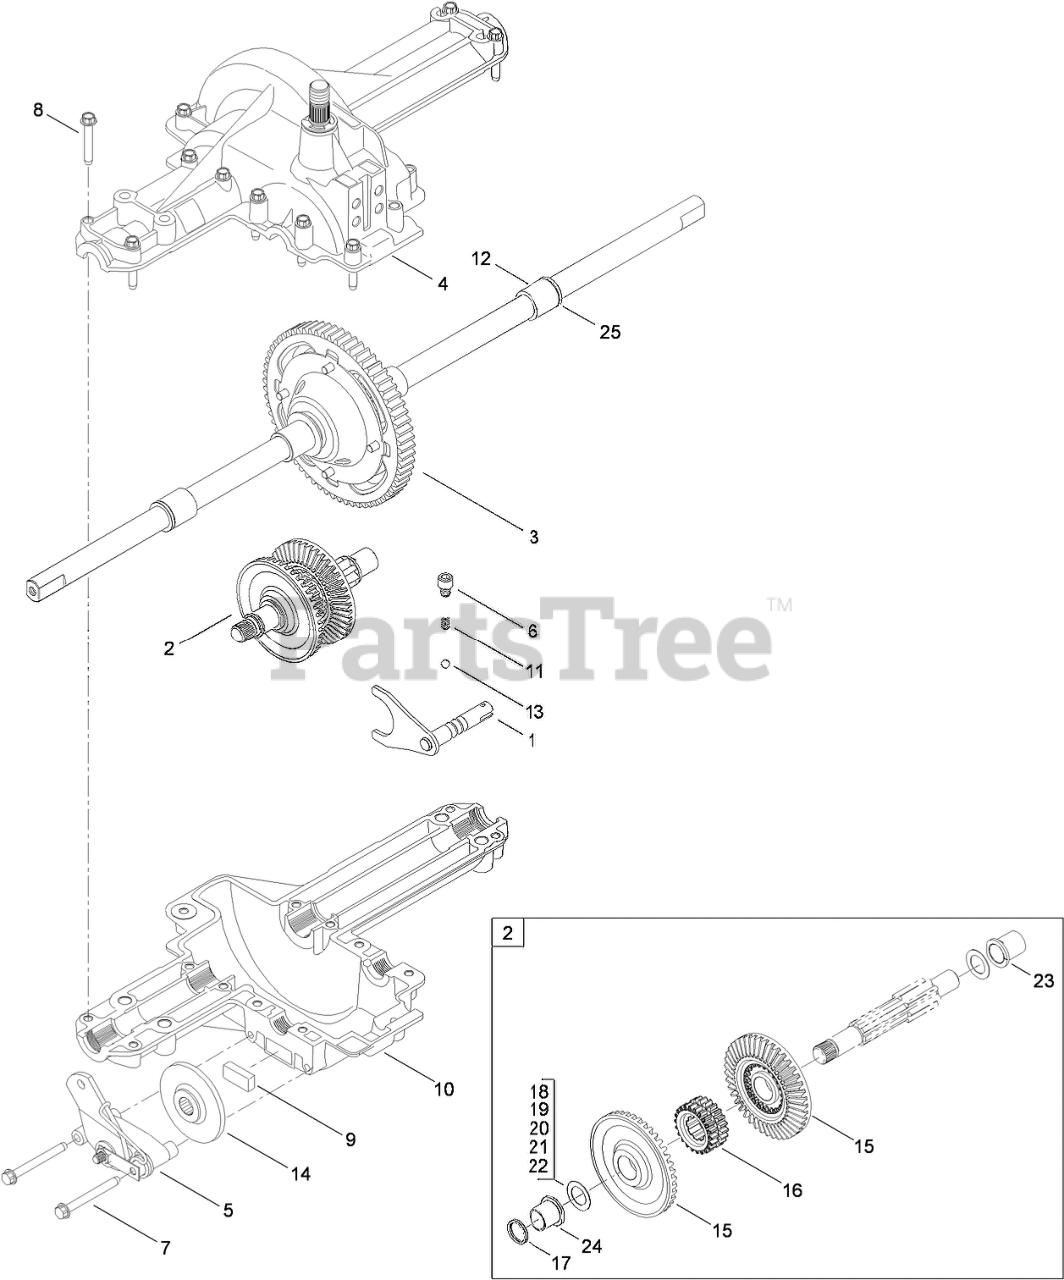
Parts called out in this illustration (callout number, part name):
1	SHIFT FORK ASM
2	DRIVE SHAFT ASM
3	DIFFERENTIAL ASM
4	UPPER HOUSING ASM
5	BRAKE ASM
6	SCREW-TAP
7	SCREW-HWH
8	SCREW-TAP
9	PUCK-BRAKE
10	HOUSING-LOWER
11	SPRING-DETENT
12	BEARING-SLEEVE
13	BALL-DETENT
14	DISC-BRAKE
15	GEAR-BEVEL, 42T (SPLINE)
16	COLLAR-CLUSTER
18	WASHER-FLAT
19	WASHER-FLAT
20	WASHER-FLAT
21	WASHER-THRUST
22	WASHER-THRUST
23	BEARING-FLANGE
24	BEARING-FLANGE
